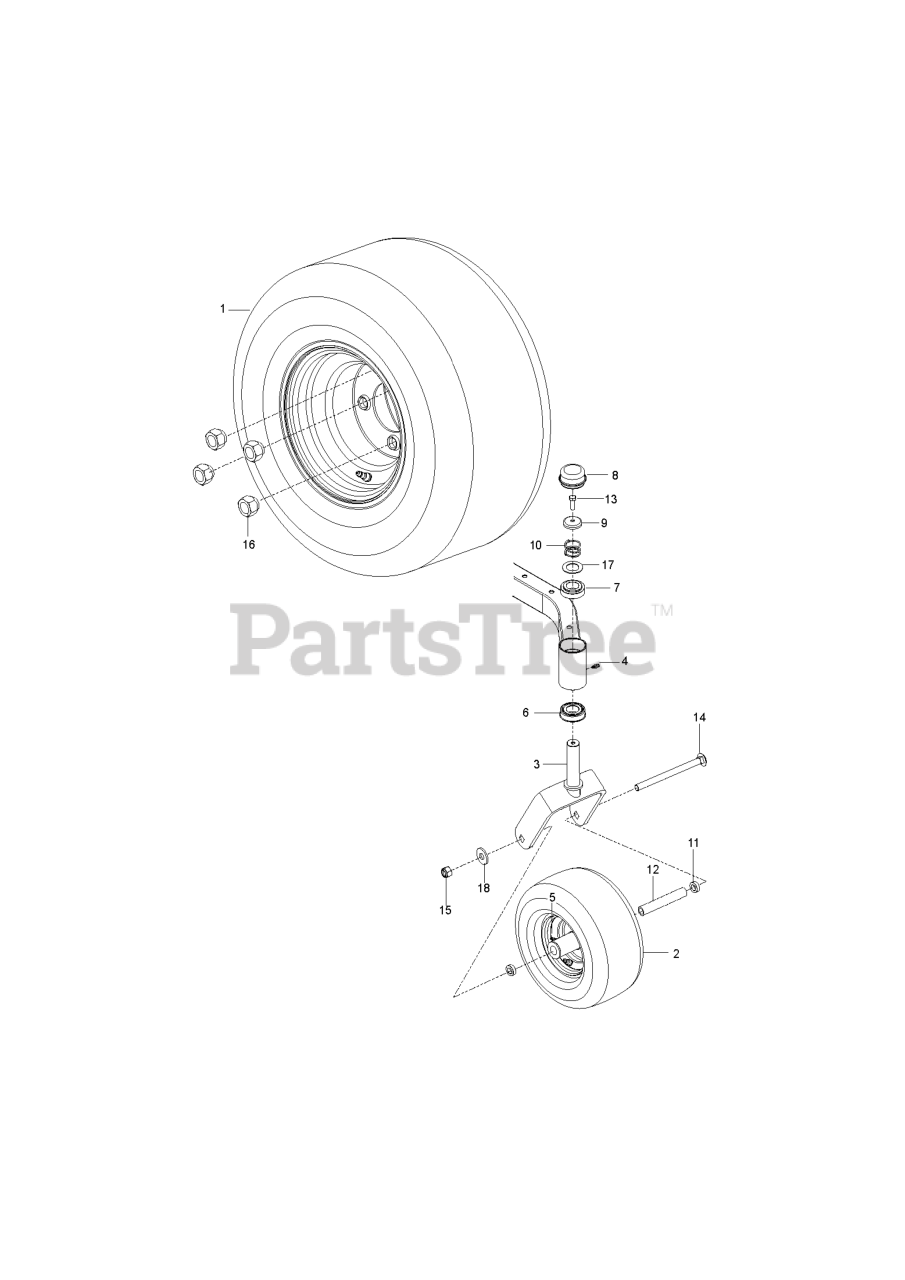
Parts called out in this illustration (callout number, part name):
1	WHEEL CARLSTAR 18X9.5-8" SILVE
1	WHEEL.A500.18 X 9.5-8.SILVER
2	WHEEL ASSY, WIDE, RZ
2	WHEEL.CARLSTAR.11X4-5".MS417
3	YOKE.PNT.CASTER.ORG
3	YOKE.CASTER.ORANGE
4	ZERK, 3/16, DRIVE IN
5	ZERK
6	BEARING FLANGED
7	BUSHING, CASTER
8	GREASE CAP
9	CASTER.PLUG
10	SPRING, CASTER
11	SPACER 5/16"
12	SPACER, PIVOT
12	SPACER.PIVOT
13	5/16-18X1 HHB G5W/NY
14	Bolts
14	Hardware
15	NUT. 1/2-13 HEX CNTRLK GR 5 ZD
16	NUT.1/2-20.UNF-2B.GR.8.YL
17	WASHER, 1.025 ID X 1.64
18	WASHER.9/16 X 1 3/8 X 12 GA.
